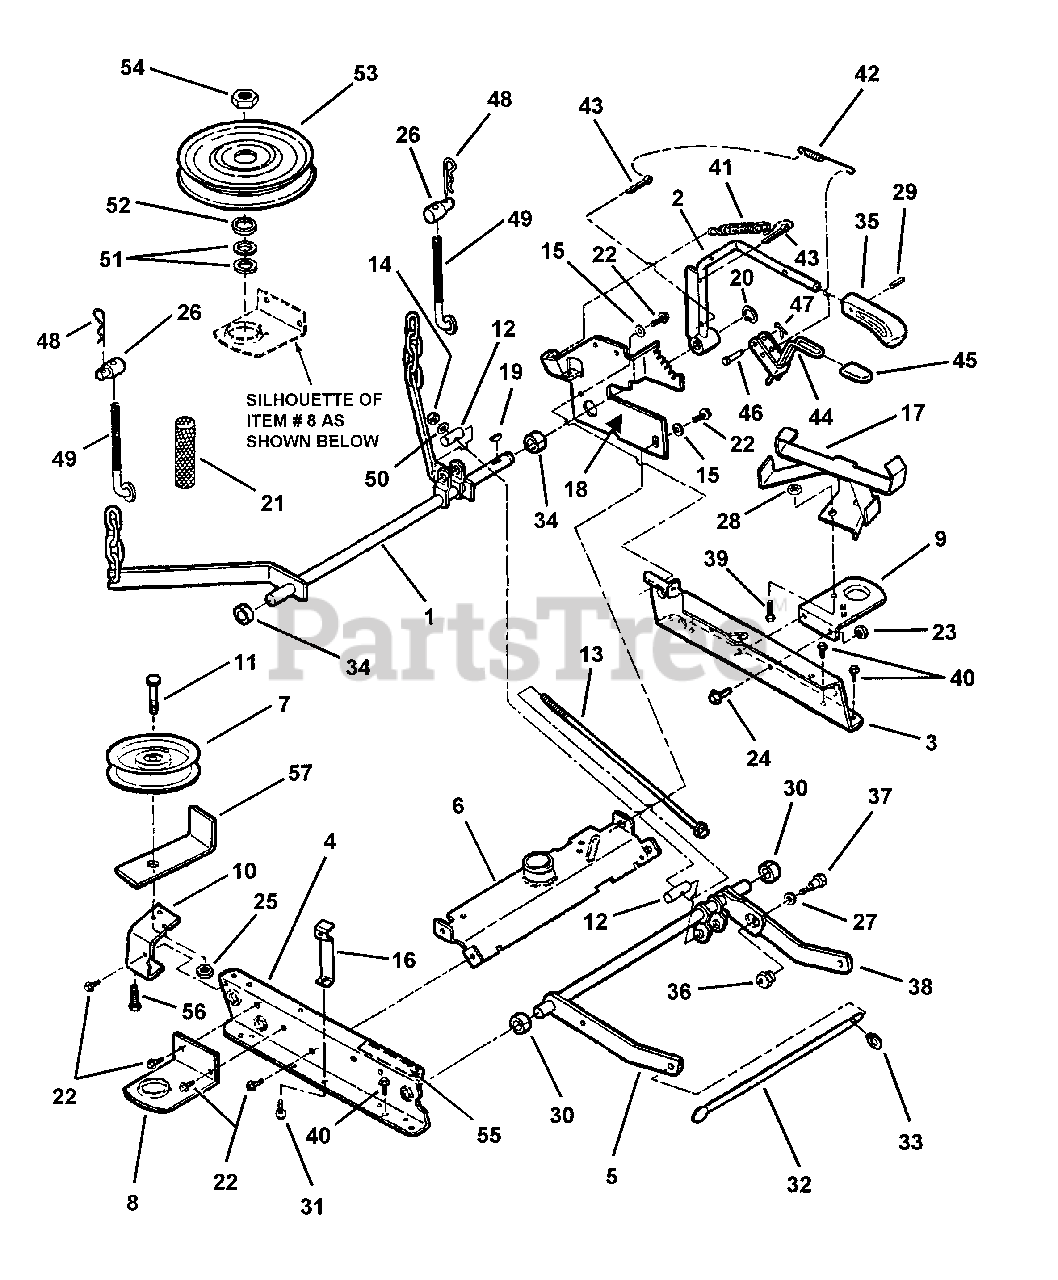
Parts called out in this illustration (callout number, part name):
1	ASSEMBLY, Rear Lift Arm
2	LEVER, Height Adjustment Lift
3	RAIL, Left Half
4	RAIL, Right Half
5	STRUCTURE, Front Lift Arm
6	BRACE, Weldment
7	PULLEY, 4-1/8" Flat Idler, .375" ID
8	SPINDLE, Brace (Right)
9	SPINDLE, Brace (Left)
10	BRACKET, Cover
11	SCREW, 3/8-16 x 1-1/2" Hex Head Cap
12	PIVOT
13	ROD, Leveling .375-16 x 16
14	NUT, 3/8-24 Hex Top Lock
15	WASHER, 3/8 Internal Tooth Lock
16	GUIDE, Belt (Rod)
17	GUIDE, Belt, 42" Rear Engine Rider
18	QUADRANT, Lift Lever
19	KEY, 3/16 x 7/8" Woodruff
20	RING, 3/4 Retaining
21	COVER, Chain
22	SCREW, 3/8-16 x 3/4" Self-Tapping
23	NUT, 3/8-16 Hex Center Lock
24	SCREW, 3/8-16 x 3/4" Hex Head Cap, Grade 5
25	NUT, 3/8-16 Hex Nyloc
26	SWIVEL, Adjustable
27	WASHER, 3/8 Internal Tooth Lock
28	NUT, 3/8-24 Hex Lock
29	PIN, 3/16 x 3/4" Roll
30	RING, Red (.36" wide)
31	SCREW, 5/16-18 x 1/2" Hex Washer Self-Tap
32	SUPPORT, Rod
33	RING, Retaining (.438" ext)
34	RING, Blue (.665" wide)
35	GRIP, Height Adjustment Lever
36	ECCENTRIC, Leveling
37	BOLT, 3/8-24 x 3/4" Shoulder
38	ARM, Front Lift (Left Side)
39	BOLT, 3/8-16 x 1" Hex Flange Lock
40	BOLT, 5/16-18 x 5/8" Hex Flange Lock
41	SPRING, Extension 5.5"
42	SPRING, Latch 5.65"
43	COTTER-PIN, 3/16 x 1-1/2"
44	LATCH
45	GRIP, Lift Latch
46	PIN, 1/4 x 1-1/4" Clevis
47	COTTER-PIN, 1/16 x 3/4"
48	HAIRPIN, 3/32 x 1-1/2"
49	ADJUSTER, Chain
50	WASHER, 3/8" Flat
51	WASHER, 3/4 Flat
52	SPACER, 3/4" I.D.
53	PULLEY, 5" O.D.
54	NUT, 3/4-16 Hex Jam
55	DECAL, Blade ON/OFF
56	BOLT, 5/16-18 x 5/8" Hex Washer Head, Self-Tap
57	GUIDE, Belt
